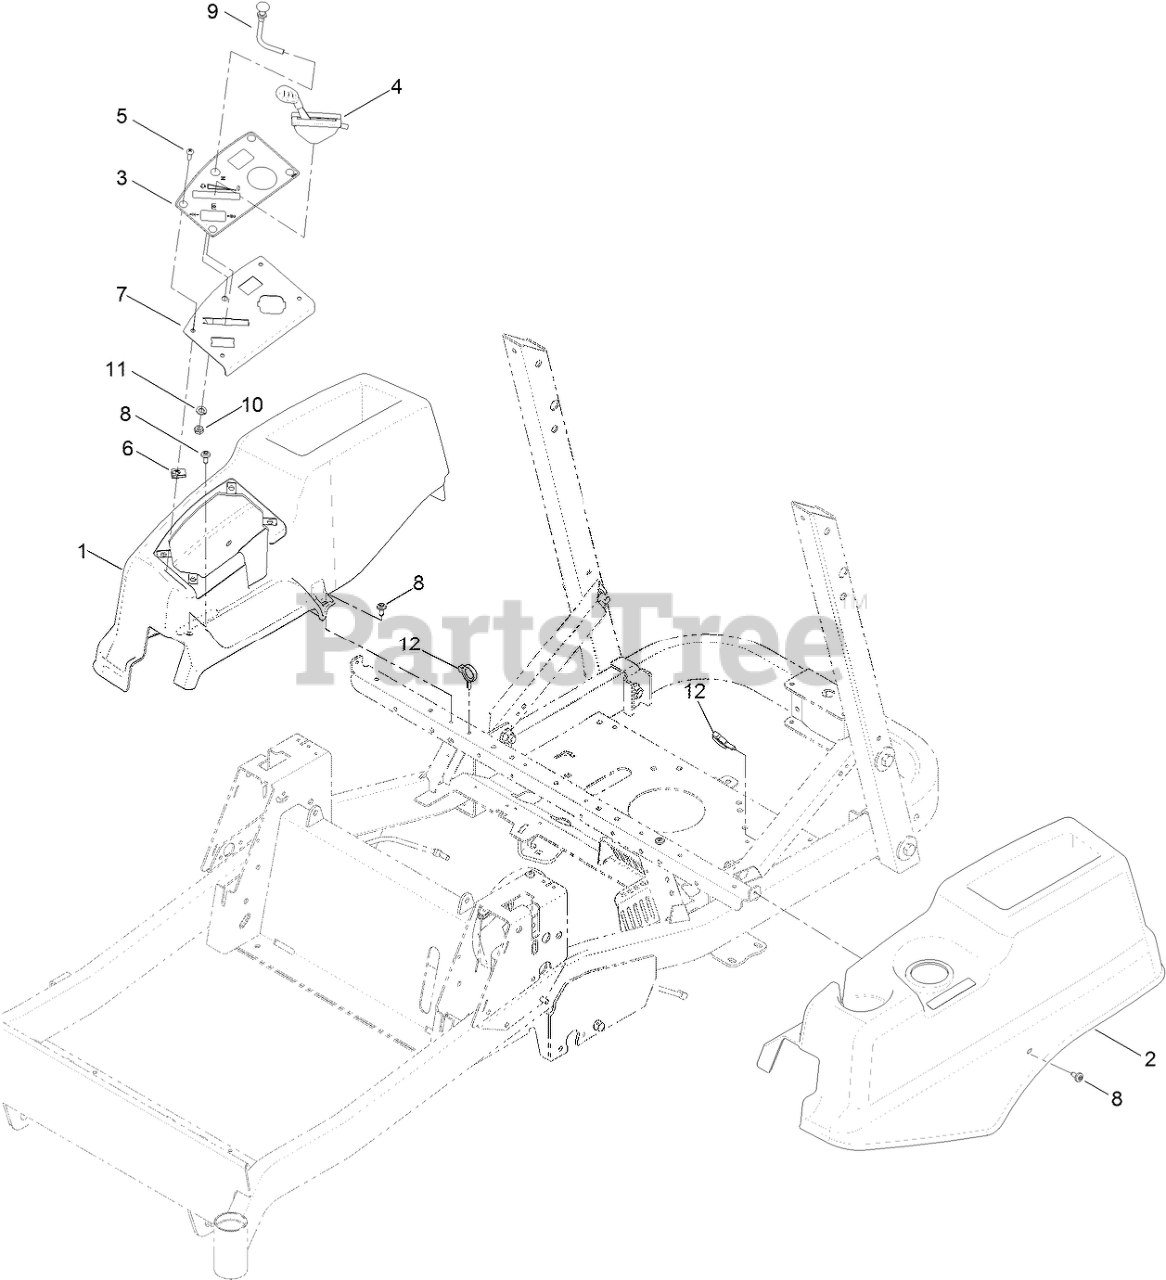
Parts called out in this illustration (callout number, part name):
1	POD-RH
2	POD-LH
3	DECAL-PANEL, CONTROL
4	CABLE-THROTTLE
5	SCREW-PRH
7	PANEL-CONTROL
8	SCREW-SHOULDER
9	CABLE-CHOKE
10	WASHER-LOCK
11	NUT-HJ
12	CLAMP-HOSE
